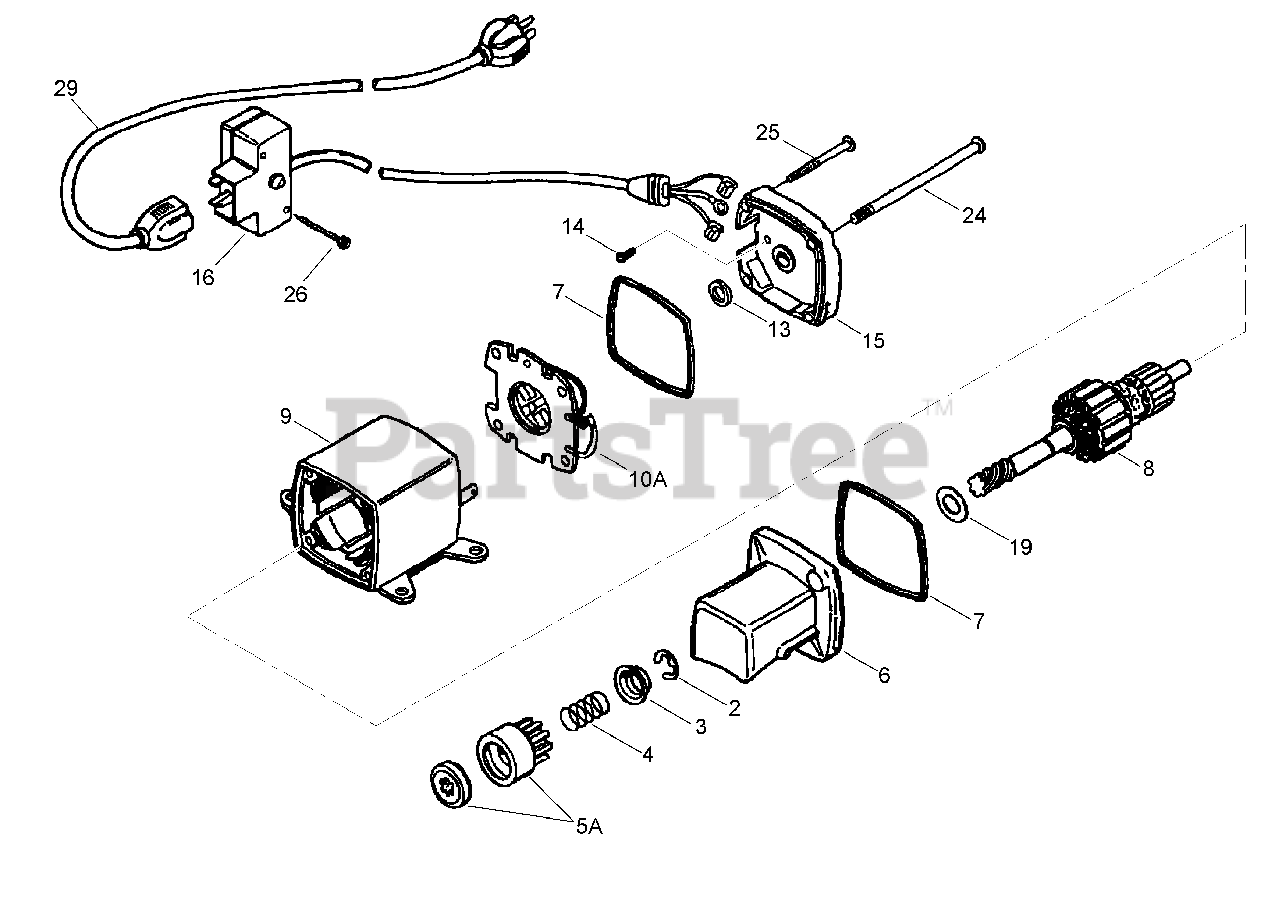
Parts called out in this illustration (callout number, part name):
2	Retainer-Ring
3	Retainer-Spring
4	Spring-Anti Drift
5A	Nut and Gear ASM (Includes 2)
6	Drive End Cap Asm (Includes 7)
7	O-Ring
8	Armature
9	Housing Asm (Must Purchase Complete Motor)
10A	Brush Card ASM
13	Washer-Thrust
14	Screw-Ground
15	Commutator End Cap ASM
16	Switch Box Asm
19	Washer-Thrust
24	Bolt-Case
25	Screw-Ground
26	Screw (O.E.M. supplied)
29	Cord-Extension (10-6) (Ref to engine parts list for mtg hardware)
